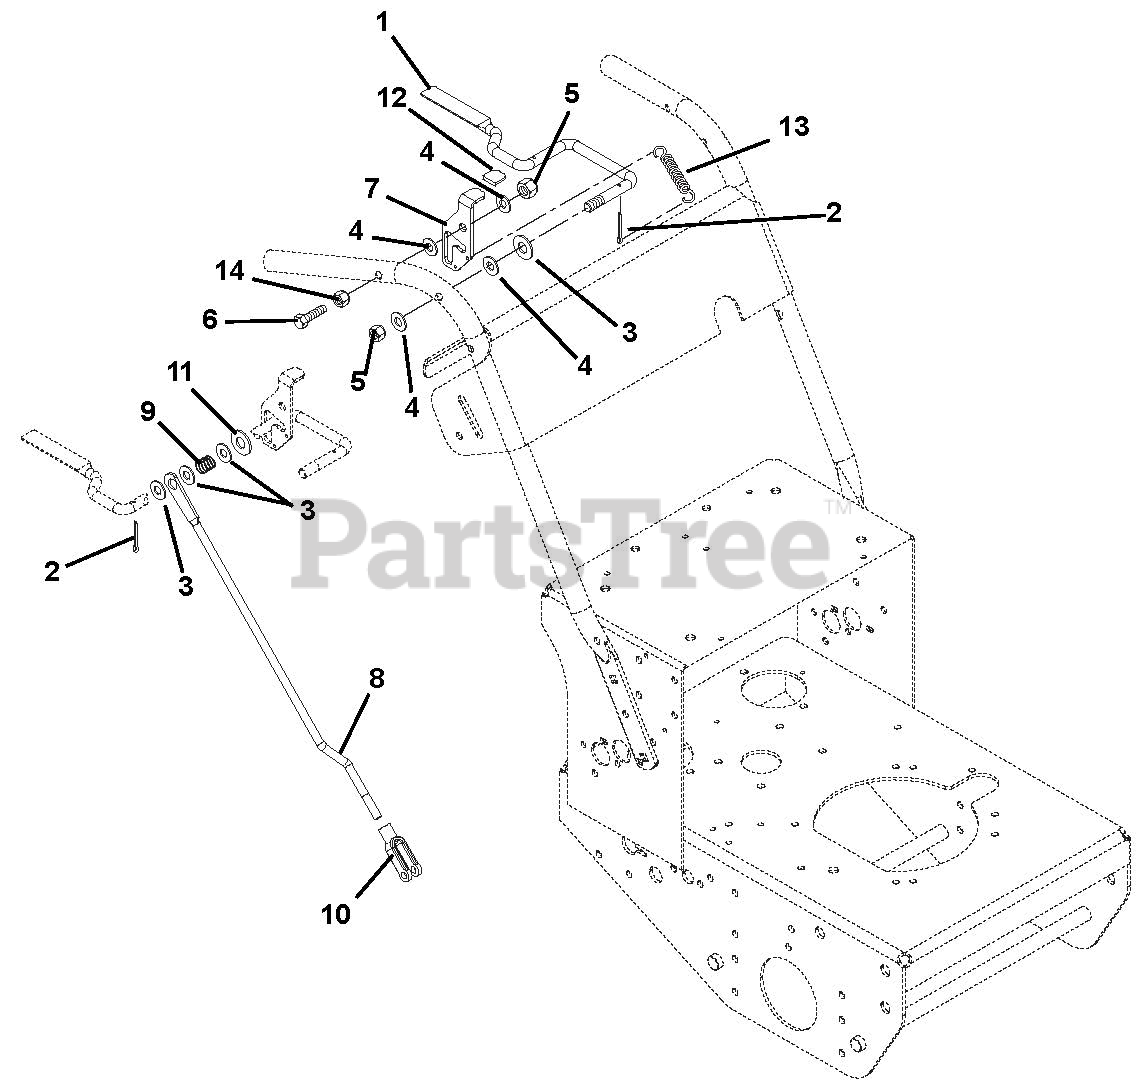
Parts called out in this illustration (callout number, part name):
1	Lever, Hand Control Left Hand
1	Lever, Hand Control Right Hand
2	Pin-Cotter .09 x .75
3	Washer-Flat-Steel .406 x .812 x .065
4	Washer-Flat-Nylon .375 x .75 x .060
5	Nut-Locking-Center .38-16
6	Bolt-Hex .38-16 x 2.50 Grade 2
7	Latch, Right Hand Thumb
7	Latch, Left Hand Thumb
8	Rod, Steering Link
9	Spring-Compression .045 x .60 x .75
10	Clevis, .38-24 Adjustable
11	Washer-Flat-Steel .50 x 1.25 x .083
12	Grip, Thumb Latch
13	Spring-Tension .041 x .50 x 1.75
14	Nut-Locking-Jam-Center .375-16
